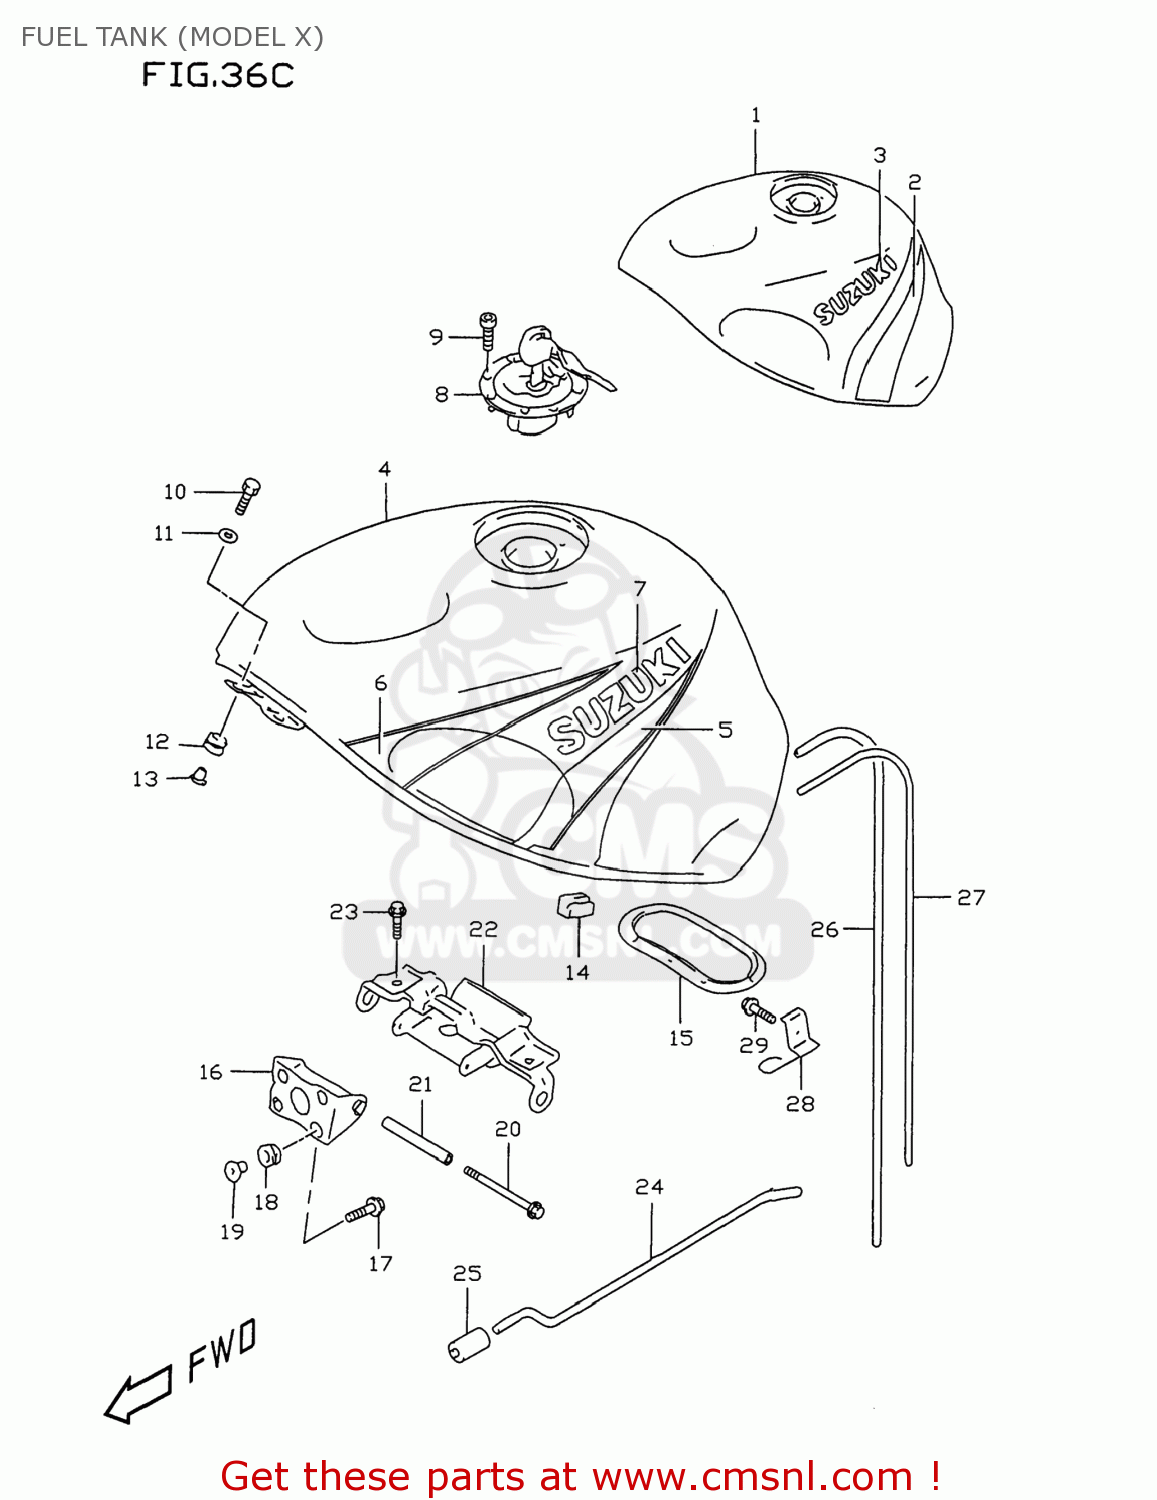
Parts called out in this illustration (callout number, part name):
1	TANK ASSY,FUEL
2	TAPE SET,FUEL TANK STRIPE
3	EMBLEM,FUEL TANK
4	TANK ASSY,FUEL
5	TAPE SET,FUEL TANK
6	TAPE SET,FUEL TANK UPR
7	EMBLEM,FUEL TANK
8	CAP SET,FUEL TANK
9	BOLT(5X20)
10	SCREW(6X25)
11	WASHER(6.5X18X1.6)
12	CUSHION
13	WASHER
14	CUSHION,FUEL TANK SIDE
15	PACKING SET,FUEL PUMP (NAS)
15A	BOLT,FUEL PUMP
16	BRACKET COMP,FUEL TANK
17	BOLT(6X20)
18	CUSHION
19	WASHER
20	BOLT
21	SPACER,FUEL TANK RR
22	BRACKET,FUEL TANK NO.2
23	BOLT
24	STAY,FUEL TANK
25	CAP,OD:11
26	HOSE(5X8.2X600)
27	HOSE(7X10.2X600)
28	GUIDE COMP,DRAIN HOSE
29	BOLT
